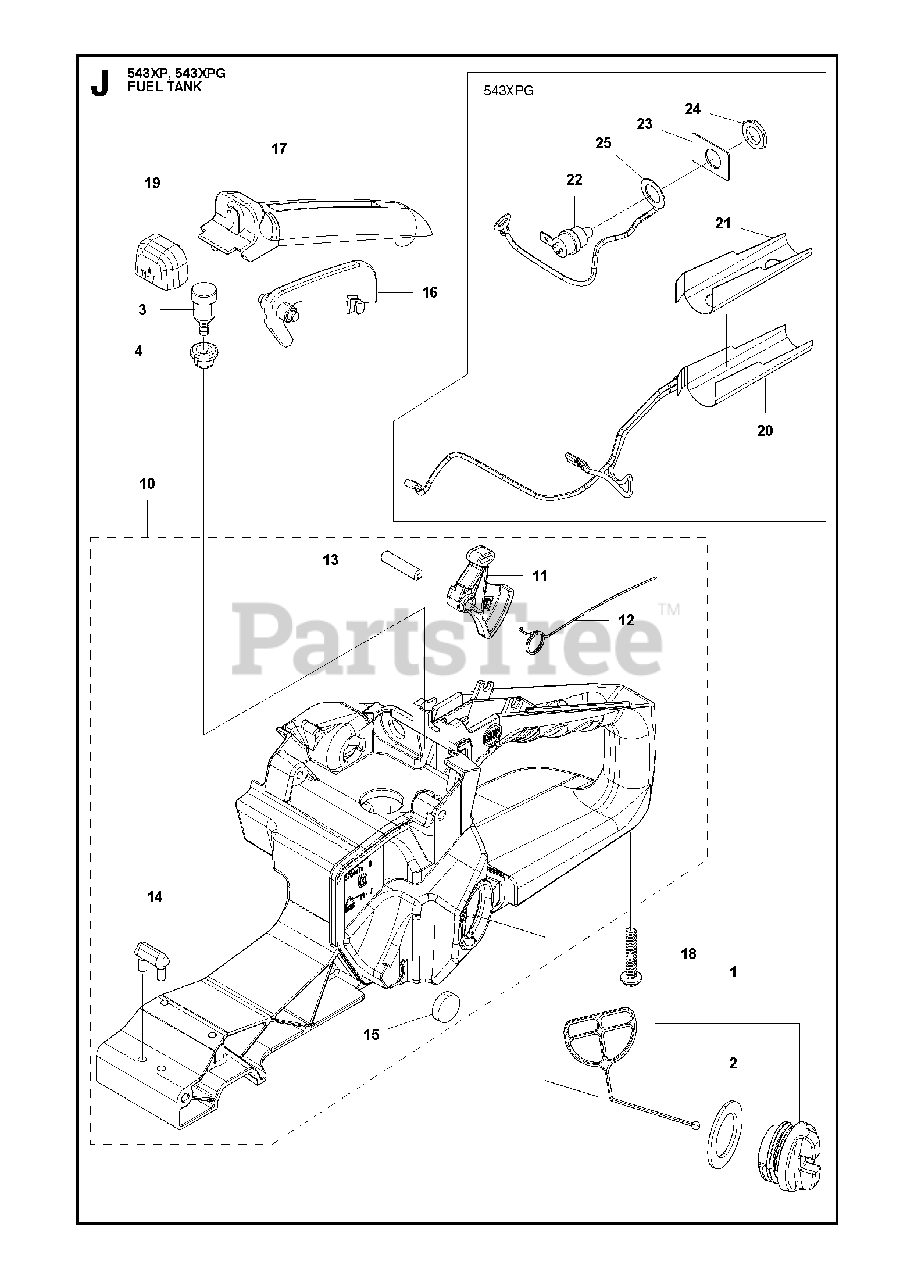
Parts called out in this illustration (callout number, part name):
1	TANK CAP ASSY
2	PACKING
4	GROMMET
10	HANDLE ASSY ORANGE_ HEATED
11	THROTTLE LEVER
12	SPRING
13	SPRING PIN
14	DAMPER(A)
15	HELPER(M) Z285033370
17	COVER GRIP
20	HEATER T202034910
21	PLATE T202034920
22	SWITCH
23	PLATE Z265534820
24	NUT Z265534830
25	CORD T202034850
